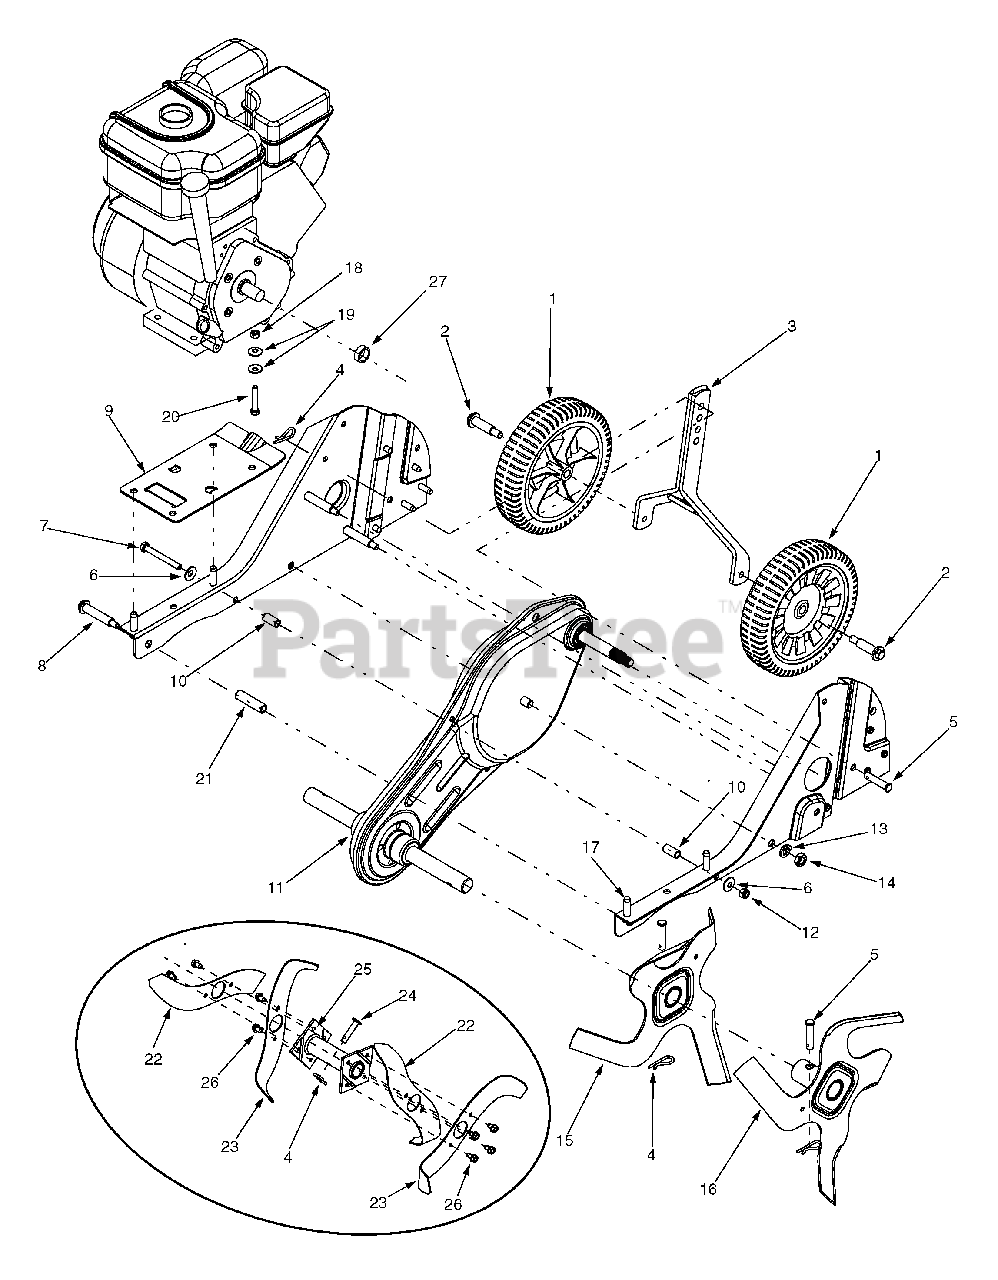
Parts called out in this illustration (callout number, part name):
1	Wheel 8 x 1.75
2	Shoulder Screw
4	Cotter Pin
5	Clevis Pin
6	Bell Washer.340 ID x.872 OD
7	Hex Cap Screw 5/16-18 x 3.0
8	Shoulder Screw
10	Spacer.47 OD x.96Lg
11	Chain Case Assembly
12	Hex Lock Nut 5/16-18
13	Lock Washer 7/16
14	Jam Nut 7/16-20
17	Hex Washer Screw 3/8-16 x 1.25
18	Hex Nut 5/16-18
19	Bell Washer.340 ID x.872 OD
20	Hex Cap Screw 5/16-18 x 1.75
21	Spacer, .51 x .69 x 1.97
27	Spacer, .790 x .347
